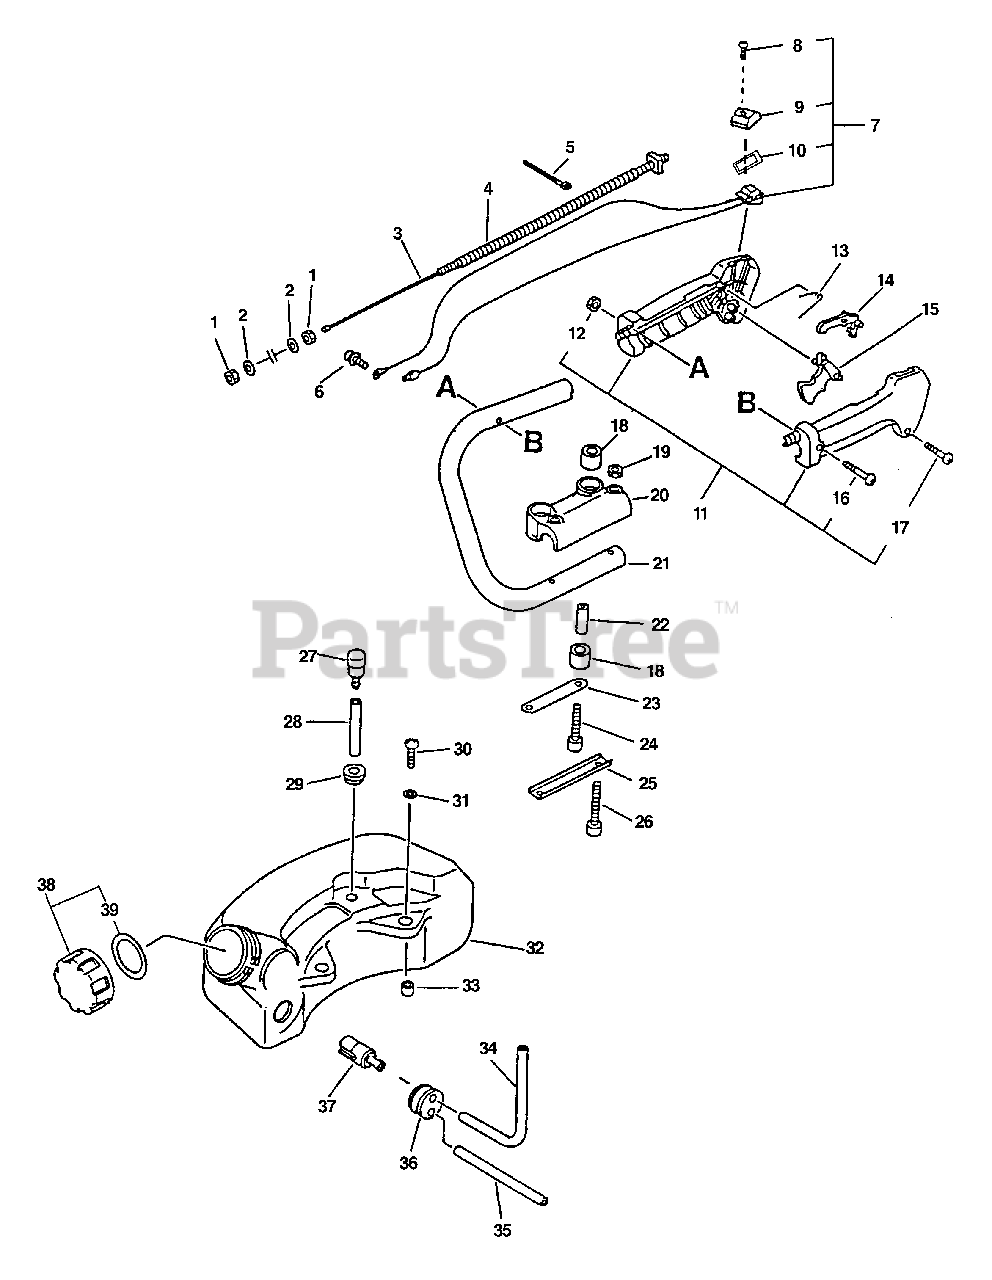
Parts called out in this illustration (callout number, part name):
2	WASHER 6.5×11.5×0.8
3	CABLE, THROTTLE
5	TIE, CABLE
6	SCREW 5×10
7	IGNITION SWITCH ASSY
8	SCREW 3×10
9	KNOB, SWITCH - ORANGE
10	LABEL, SWITCH
11	CONTROL HANDLE KIT
12	NUT M5
13	SPRING, TORSION
14	LOCKOUT, THROTTLE
15	TRIGGER, THROTTLE
16	SCREW 5×30
17	SCREW 3×25
19	NUT, LOCK M5
20	SUPPORTER, HANDLE
21	HANDLE, REAR
22	SPACER
23	PLATE, EYE
24	BOLT 5×45
26	BOLT M5×35
27	VENT ASSY
28	PIPE, FUEL
29	GROMMET
30	SCREW 5×16
31	WASHER 5.5×12×0.8
32	TANK, FUEL
33	SPACER 6.2×7.8×6
34	PIPE, FUEL
35	PIPE, FUEL RETURN 3×6×110
36	GROMMET, FUEL
37	FILTER, FUEL
38	CAP ASSY, FUEL
39	GASKET, FUEL CAP
